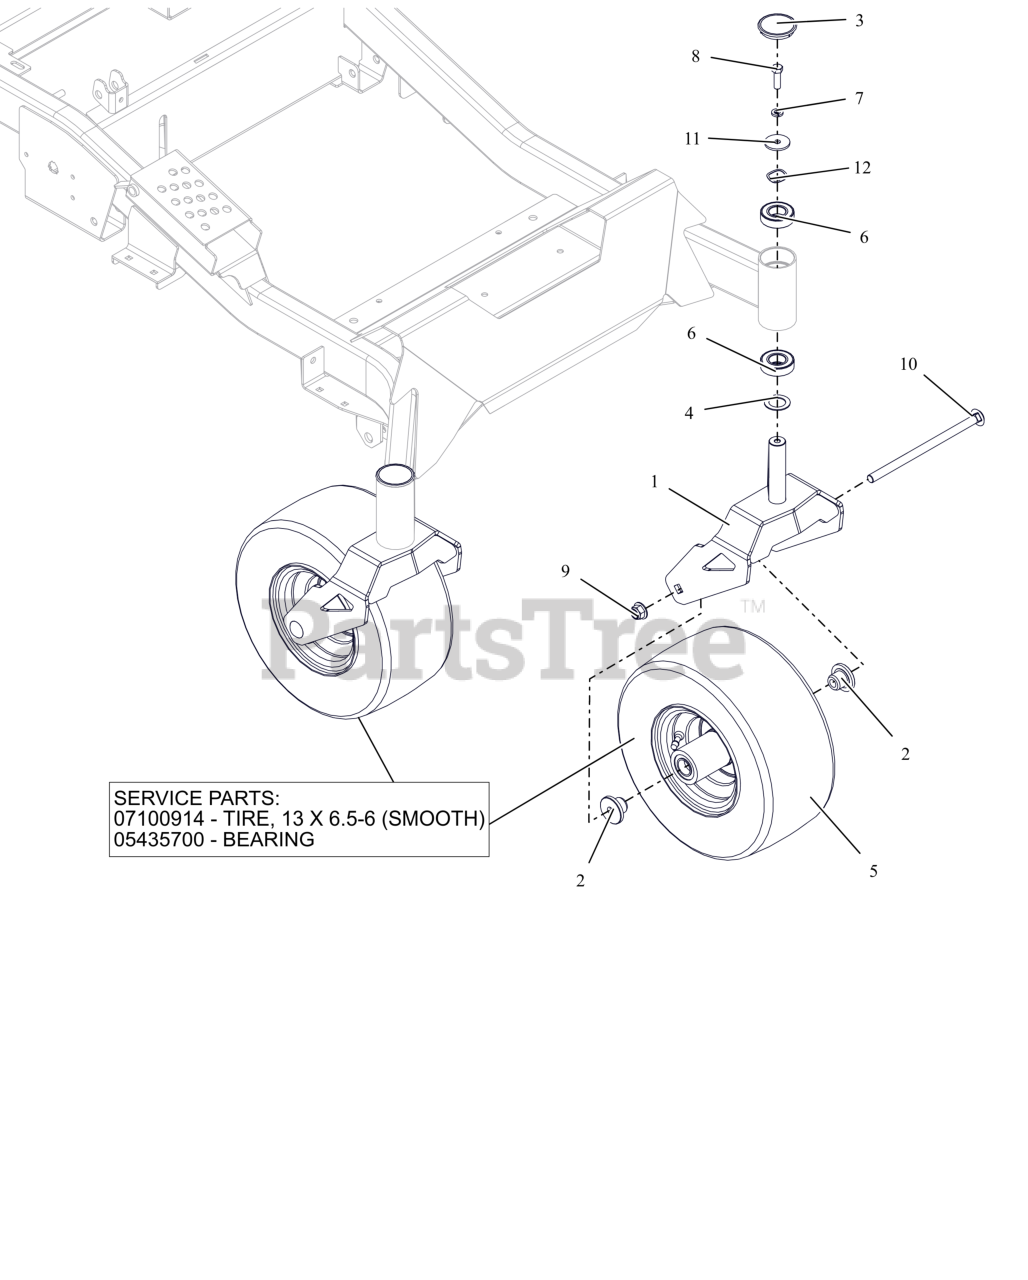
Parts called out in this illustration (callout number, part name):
1	WLDMT, HD CASTER FORK
2	SPACER, FRONT WHEEL
3	CAP, DUST
4	WSHR-HRD-THRS 1.007X1.542X.062
5	ASM, WHL/TIRE 13X6.50-6
5	TIRE, 13X6.50-6 SMOOTH
5	BRG, 25MM ID X 52MM OD X 15MM
6	BRG,BALL 1.00X2.00X.563(1641)
7	WSHR, LK-HVY .375X.115 ZCC
8	BLT, HEX .38-16X1.25 G5 ZCC
9	NUT,NYL-FLG .50-13 GF ZCC
10	BLT, RHSN .50-13X9.00 G5 ZCC
11	WSHR, FLT .380X1.50X.125 ZCC
12	WSHR-WAVE 1.0X1.25X.028 .145FH
